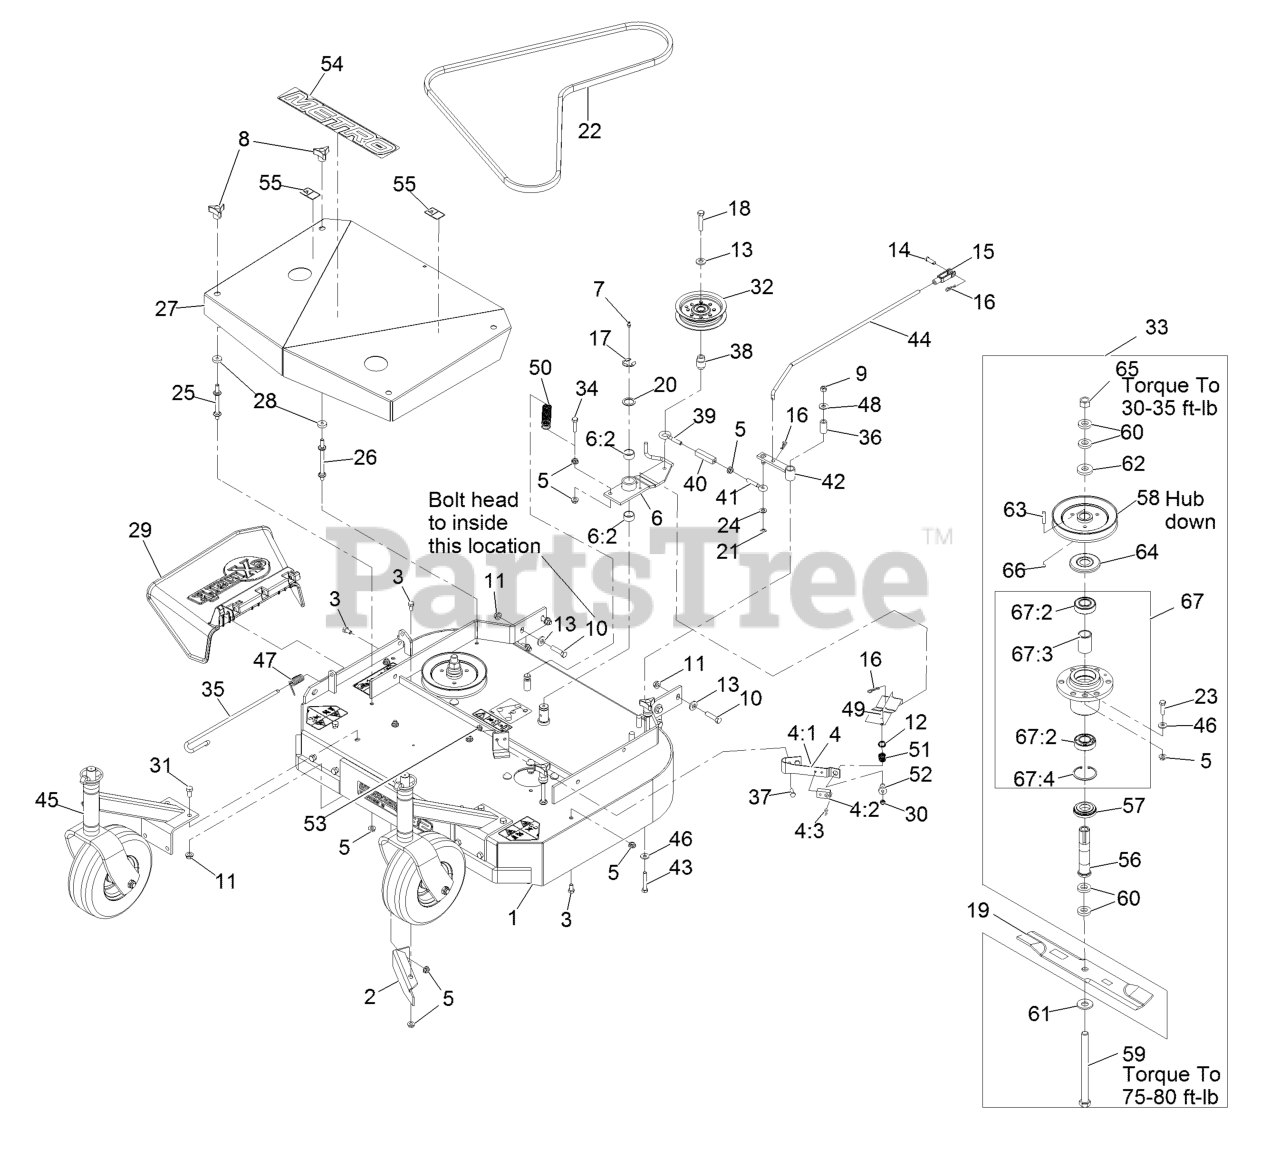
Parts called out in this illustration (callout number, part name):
1	Deck W/Decals And Dogleg
2	Baffle-Dogleg
3	Screw-HH 5/16-18 X 5/8
4	Pad And Spring ASM
4:1	Pad-Brake
4:2	Spring
4:3	Rivet 3/16 X 1/2
5	Nut-Whizlock 5/16-18
6	Idler Arm ASM
6:2	Sleeve-Bearing
7	Zerk-1/4-28 Str
8	Knob-3 Prong
9	Nut-Nyloc 5/16-18
10	Screw-HH 3/8-16 X 1 1/2
11	Nut-Whizlock 3/8-16
12	Ring-Push On
13	Washer-Spring Disc 3/8
14	Pin-Clevis 5/16 X 1 49/64
15	Yoke-Adjustable
16	Hairpin-Cotter
18	Screw-HH
19	Blade, 16.25 Solid
19	Blade, 16.25 Mulching
19	Blade, 16.25 Notched
19	Blade,Low Lift 16.25
19	Blade-Extreme 2, 16.25"
20	Washer-Spindle
22	Drive Belt, (To Blades)
23	Screw-HH 5/16-18 X 1 1/4
24	Washer-5/16 SAE
25	Stud-Shield, Belt (Short)
26	Stud-Shield, Belt (Long)
27	ASM,Shield W/Decals 32 Metro
28	Washer-Belt Shield
29	Deflector-Discharge
30	Nut-Nyloc 1/4-20 Thin
31	Screw-HH 3/8-16 X 3/4
32	Pulley-Idler
33	Asm, Cutter Housing Complete
34	Screw,HH Special 5/16-18 X 1.25
35	Pin-Chute
36	Tube-Pivot
37	Screw-HH 1/4-20 X 3/4
38	Bushing-Engagement
39	Eyebolt-Thread, LH
40	Body-Turnbuckle
41	Eyebolt-Thread, RH
42	Arm-Assist, 32/36
43	Screw-HH 5/16-18 X 2
44	Arm-Assist, Linkage
45	Caster/Mount, Complete
46	Washer-Spring Disc 5/16
47	Spring, Torsion
48	Washer-5/16 Std
49	Rod-Brake
50	Spring-Extension
51	Spring-Compression
52	Spacer-Flanged
53	Nut-Nyloc 1/4-20
54	Decal-Metro
55	Decal-Warning
56	Tube-Spindle, Short
57	Spacer-Guard Bottom
59	Screw-Cap, HH
60	Spacer-Blade Drive
61	Washer-Spring Disc 5/8
63	Key-Machine 1/4 X 3/16 X 1 1/4
64	Guard-Bearing Top
65	Nut-Hex 5/8-18
66	Setscrew-5/16-18 X 3/8
67	Asm, Cutter Housing W/Bearings
67	Cutter Housing ASM
67:2	Bearing-Jackshaft
67:3	Spacer-Bearing
67:4	Ring-Retaining
